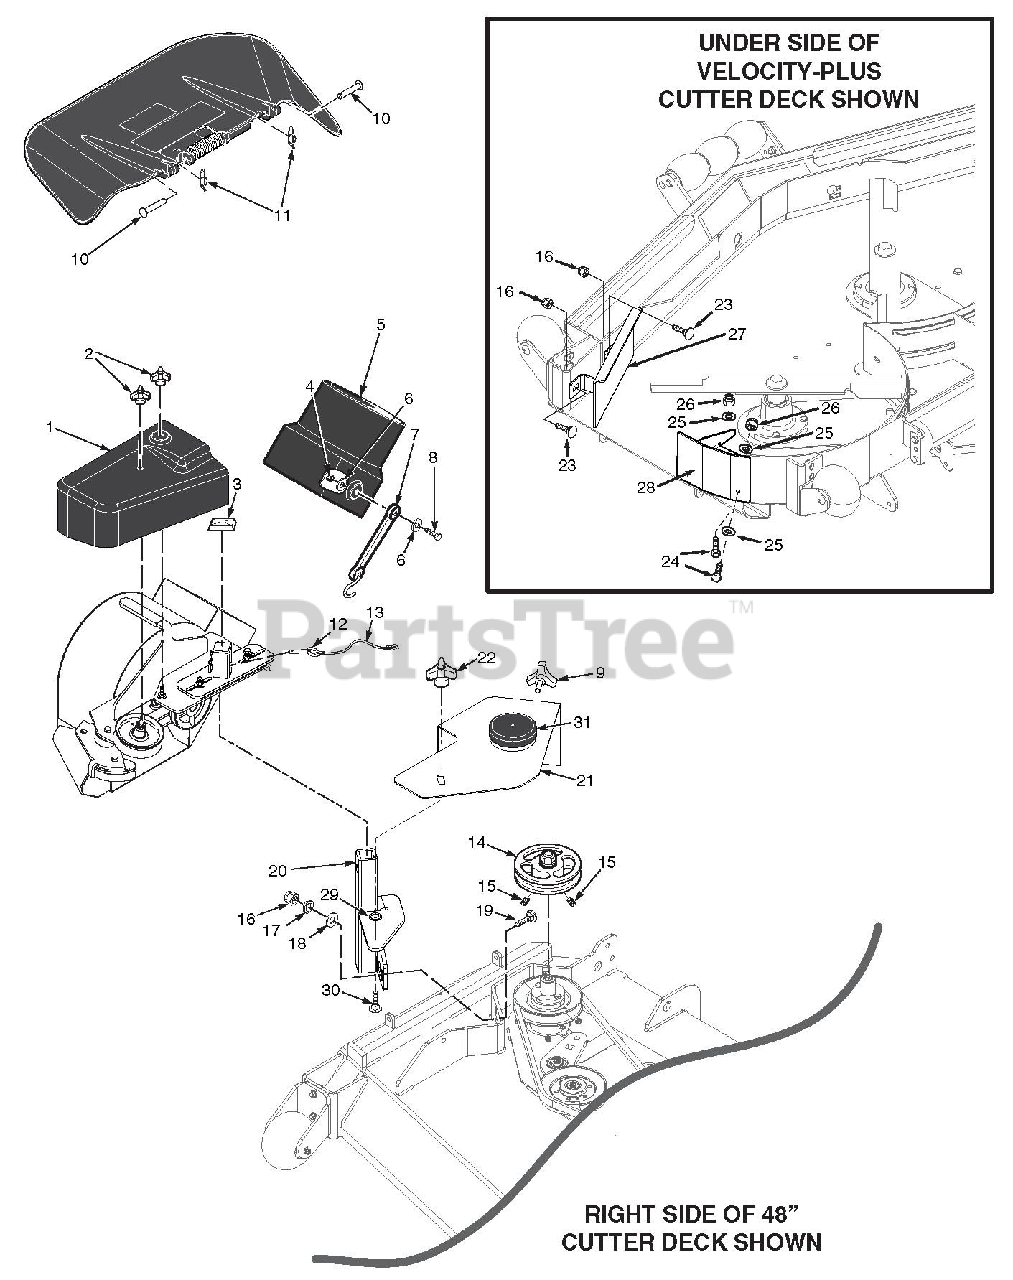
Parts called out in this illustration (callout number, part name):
1	Belt Cover, 48"
1	Belt Cover, 52"
2	Wingnut, Plastic 3/8" Small
3	Cap, Square Vinyl
4	Nut, Elastic Stop 1/4-20
5	Adapter, Blower GC-STC
6	Flatwasher, 1/4-.312 x .750 x .065
7	Rubber Strap 7-3/4"
8	Bolt, Hex Head 1/4-20 x 1-1/4"
9	Knob W/Stud, 3/8-16 x 1-1/4"
10	Clevis Pin, 5/16 x 1-1/2"
11	Pin, Rue Cotter 5/16 Dia.
12	Pin, Ring 1/2 x 2-1/4"
13	Lanyard
14	Pulley, 4.0" Dia. 1.125 Bore
15	Setscrew, 5/16-18 x 3/8"
16	Nut, Elastic Stop 3/8-16
17	Lockwasher, 3/8"
18	Flatwasher, 3/8-.391 x .938 x .105
19	Bolt, Carr. 3/8-16 x 1-1/4" Grade 5
20	Mounting Post Weldment, Blower
21	Belt Cover Assembly, w/Cap - 48"
21	Belt Cover Assembly, w/Cap - 52"
22	Wing Nut, 3/8 Plastic - Small
23	Bolt, Carriage 3/8-16 x 1"
24	Bolt, Hex Head 5/16-18 x 1"
25	Flatwasher, 5/16-.375 x .875 x .083
26	Nut, Elastic Stop 5/16-18
27	Baffle Weldment 48 / 52
28	Baffle, Turbo 48" Deck
28	Baffle, Turbo 52" Deck
29	Nut, Push-On 3/8 Thread
30	Bolt, Carriage 3/8-16 x 1-1/4"
31	Cap, Spindle
